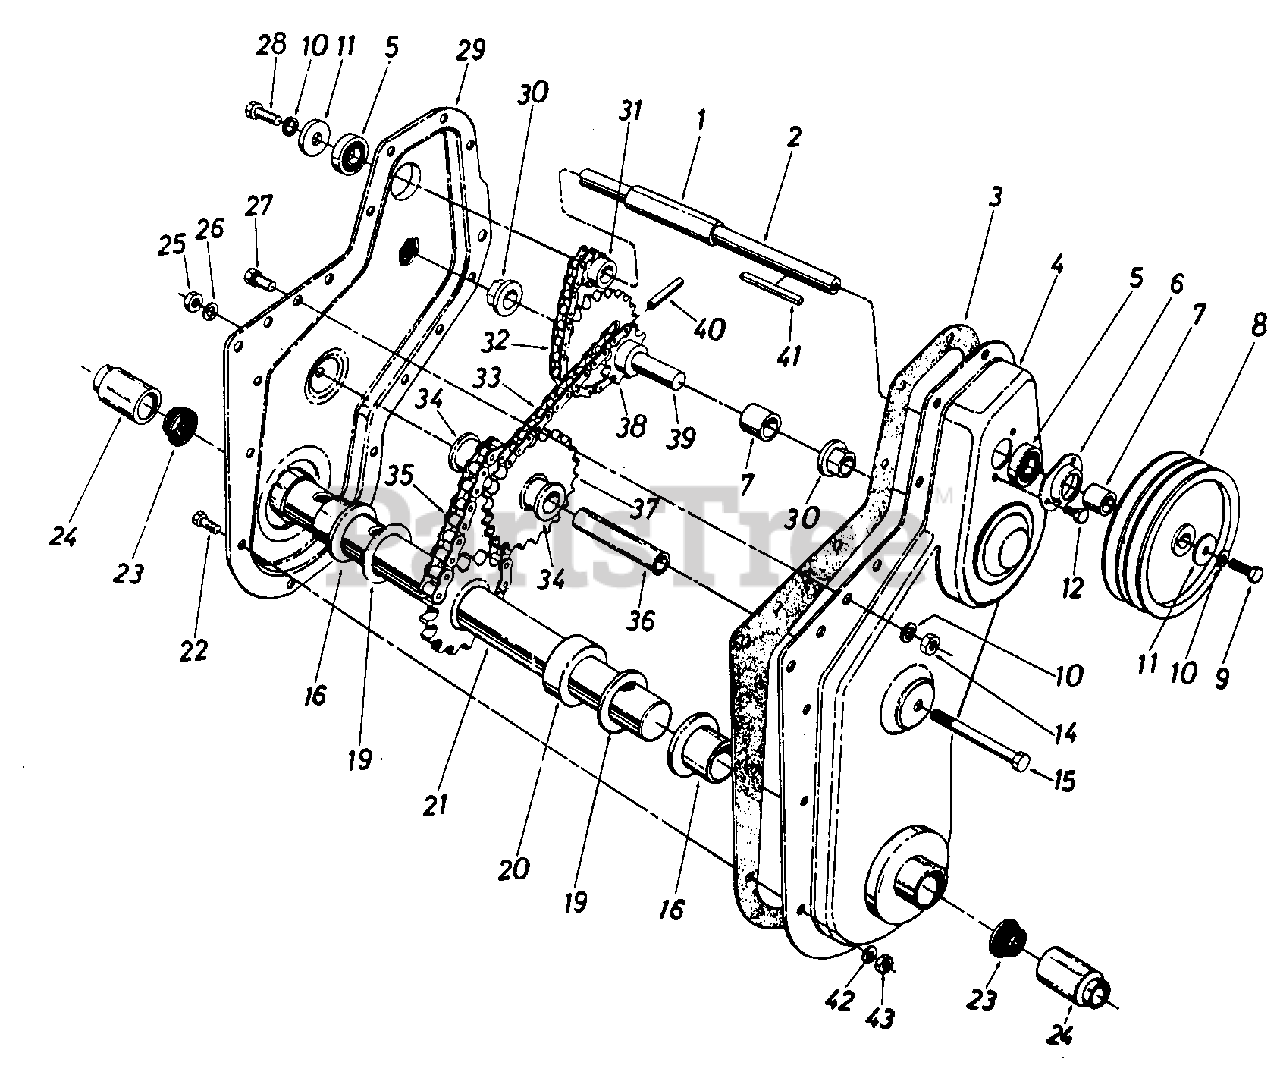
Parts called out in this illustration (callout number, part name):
2	SHAFT-JACK
3	GASKET
4	CHAIN CASE HALF-LH
5	BEARING-BALL
6	HOUSING-BRG
7	SPACER-.635 ID X .88 OD X 1.03
9	SCREW-HEX 5/16-18 X 10 SPEC
10	WASHER-LOCK-5/16
11	WASHER-FL-.312 X 1.125 X .125
12	SCREW-HEX WASH SF TAPP
14	NUT-HEX 5/16-18
15	SCREW-HEX 3/8-16 X 3.25
16	BEARING-KING PIN
19	WASHER-FL-1.03 ID X 1.62 X .03 HD
21	SHAFT-TINE
22	SCREW-HEX 1/4-28 X .62
24	CAP-DUST
25	NUT-HEX 3/8-16
26	WASHER-LOCK-3/8
27	SCREW-HEX SEMS 5/16-18 X 1.00
28	SCREW-HEX 5/16-18 X .62
29	CHAIN CASE HALF-RH
30	BEARING-HEX FLANGE
31	SPROCKET ASSY-10T
32	#41 CHAIN 1/2 PITCH X 34 LINKS E
33	#420 CHAIN 1/2 PITCH X 48 LINKS
34	BEARING-FLANGE .626 ID
35	#50 CHAIN 5/8 PITCH X 28 LINKS
36	SHAFT-SPROCKET
37	SLEEVE ASSY-SPRKT
38	SLEEVE ASSY-SPRKT
39	SHAFT-SPROCKET
40	PIN-SPRING SPIRAL 1/4X1.5 HEAVY DT
41	KEY-SQ 3/16X1.50
42	LOCK WASHER 1/4 DIA
43	NUT-HEX 1/4-28
